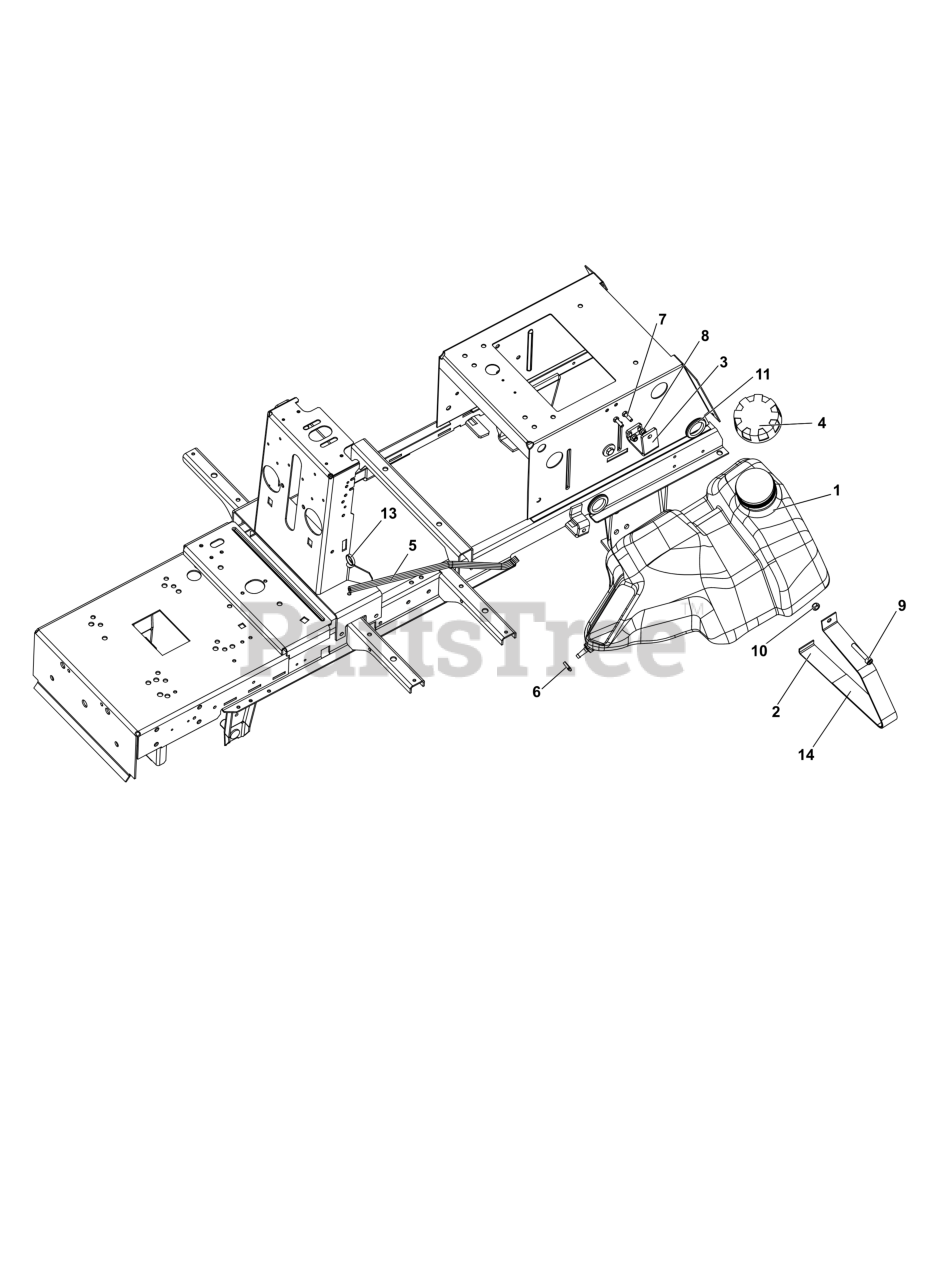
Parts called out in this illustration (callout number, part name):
1	TANK, Fuel
4	CAP, Fuel Tank
5	HOSE, Fuel
